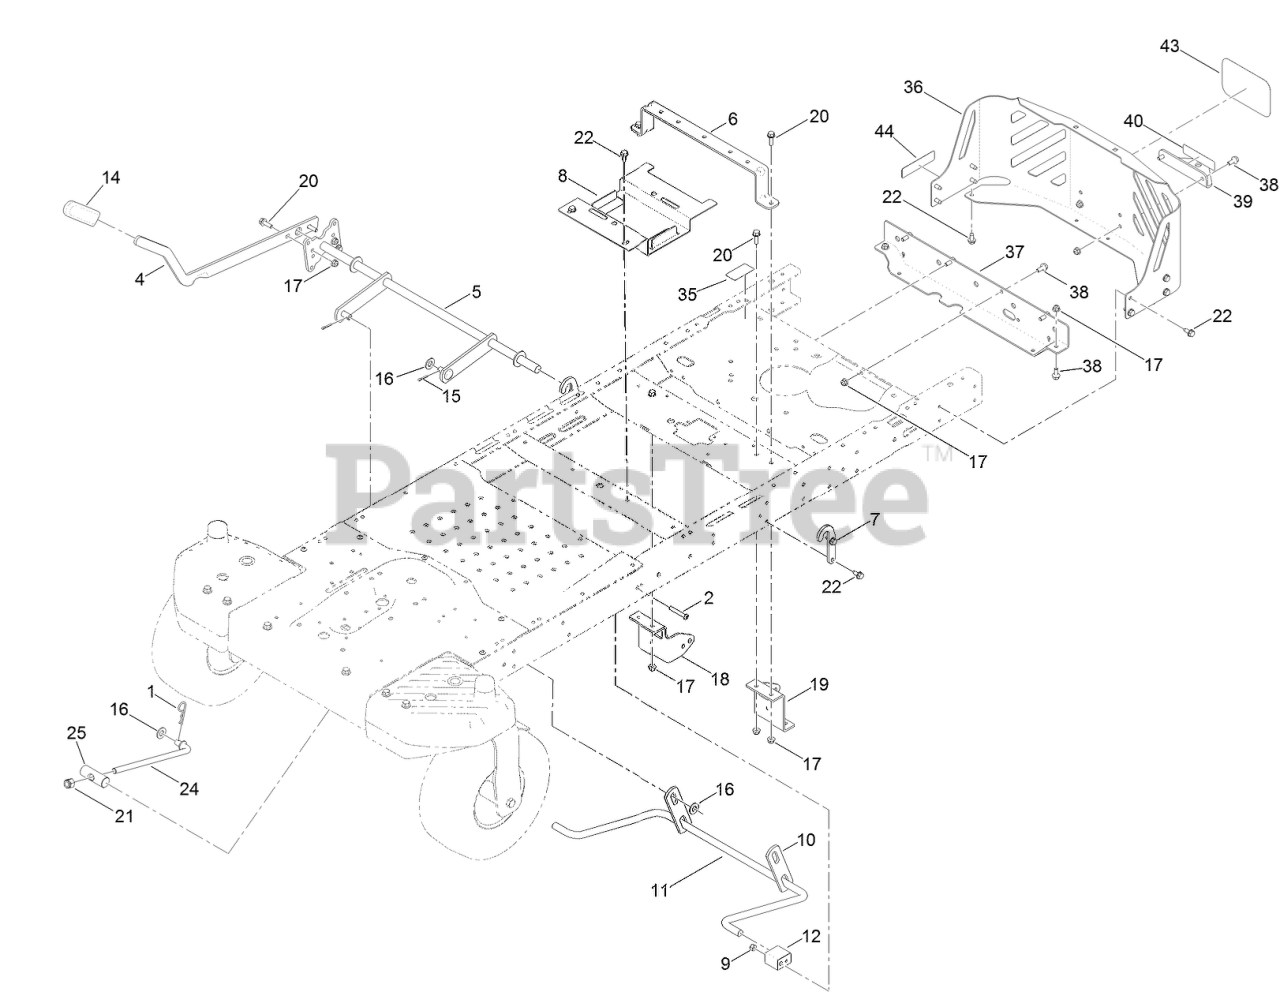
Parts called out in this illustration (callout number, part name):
1	PIN-COTTER
2	SCREW-HSBH
4	LEVER-LIFT
5	LIFT-DECK, WIDE
6	BRACE-SEAT, REAR
7	BRACKET-LIFT
8	BRACKET-BATTERY
9	NUT-LOCK, NI
10	LINK-LIFT
11	ARM-LIFT, REAR (WIDE)
12	BLOCK-PIVOT
14	GRIP-LEVER
15	PIN-COTTER
16	WASHER-FLAT
17	NUT-HF, NI
18	MOUNT-HYDRO, FRONT (RH)
19	MOUNT-HYDRO, FRONT (LH)
20	SCREW-HHF
21	NUT-HEX
22	SCREW-HWHTF
24	ROD-MOUNT, DECK
25	PIN-PIVOT
35	DECAL-BYPASS
36	GUARD-ENGINE, WIDE
37	CROSSMEMBER-REAR, WIDE
38	SCREW-HHF
39	BRACKET-HITCH
43	DECAL
44	DECAL-ARRESTER, SPARK
